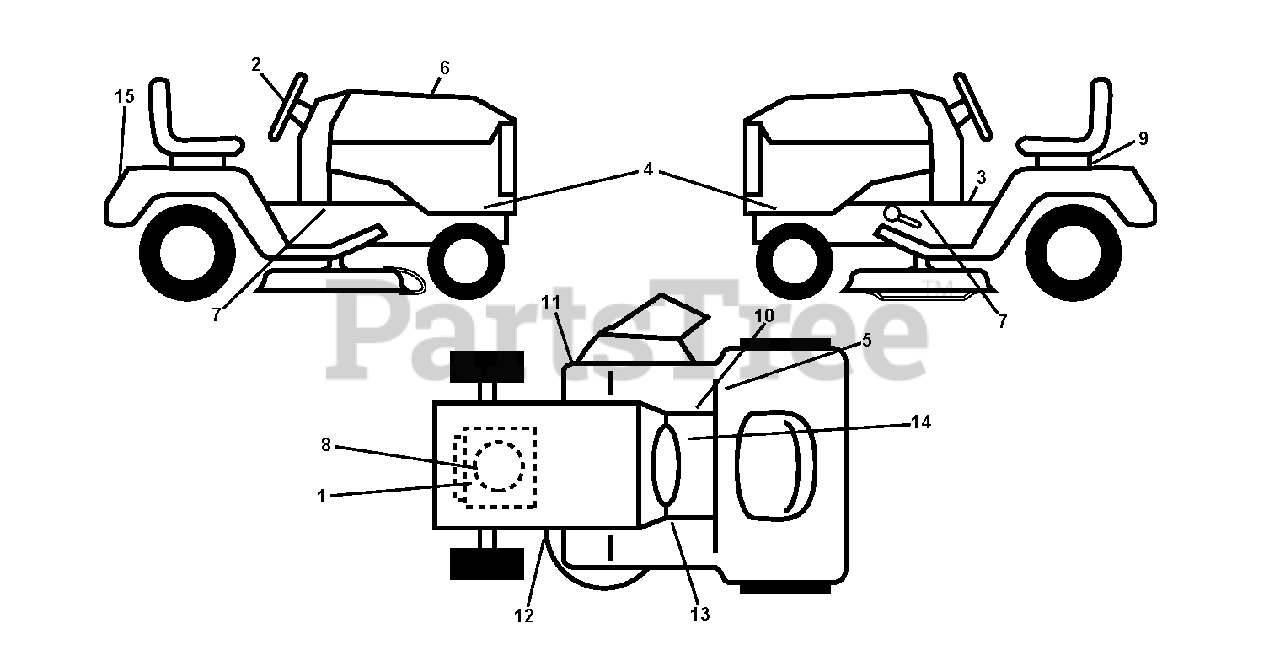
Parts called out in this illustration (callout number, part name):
9	DECAL BTRY SYMBOLS
11	DECAL.WARN.DFLECT/CTFINGR.SRD
14	DECAL PARK BRAKE
